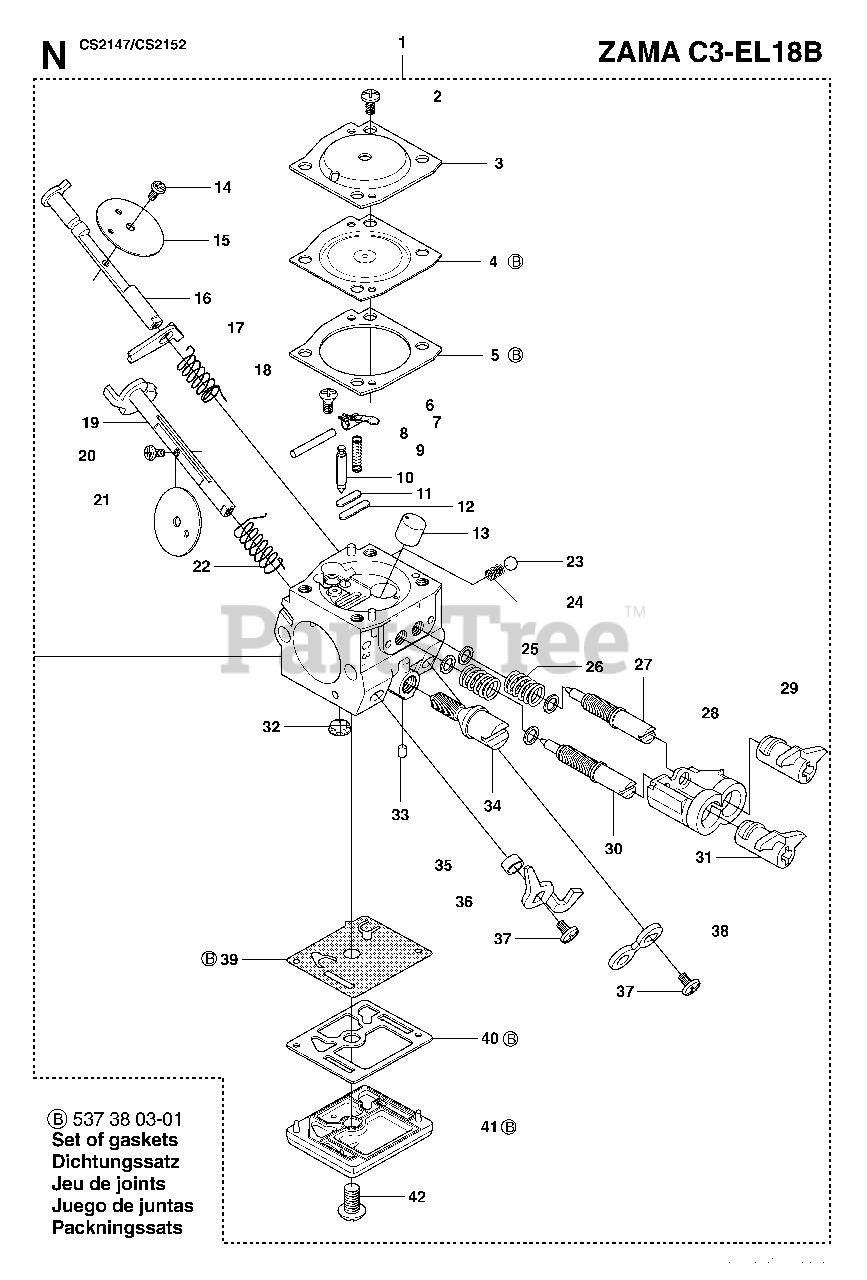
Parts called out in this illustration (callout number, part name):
1	CARBURETOR C3-EL18
4	DIAPHRAGM
8	PIN FULCRUM
15	CHOKE FLAP
16	CHOKE SHAFT
17	THROTTLE LOCK
19	THROTTLE SHAFT
21	THROTTLE FLAP
26	SPRING
29	LIMITER CAP
30	LOW SPEED NEEDLE
31	LIMITER CAP
34	IDLE SCREW
35	BUSHING *
39	PUMP DIAPHRAGM
B	GASKET SET
